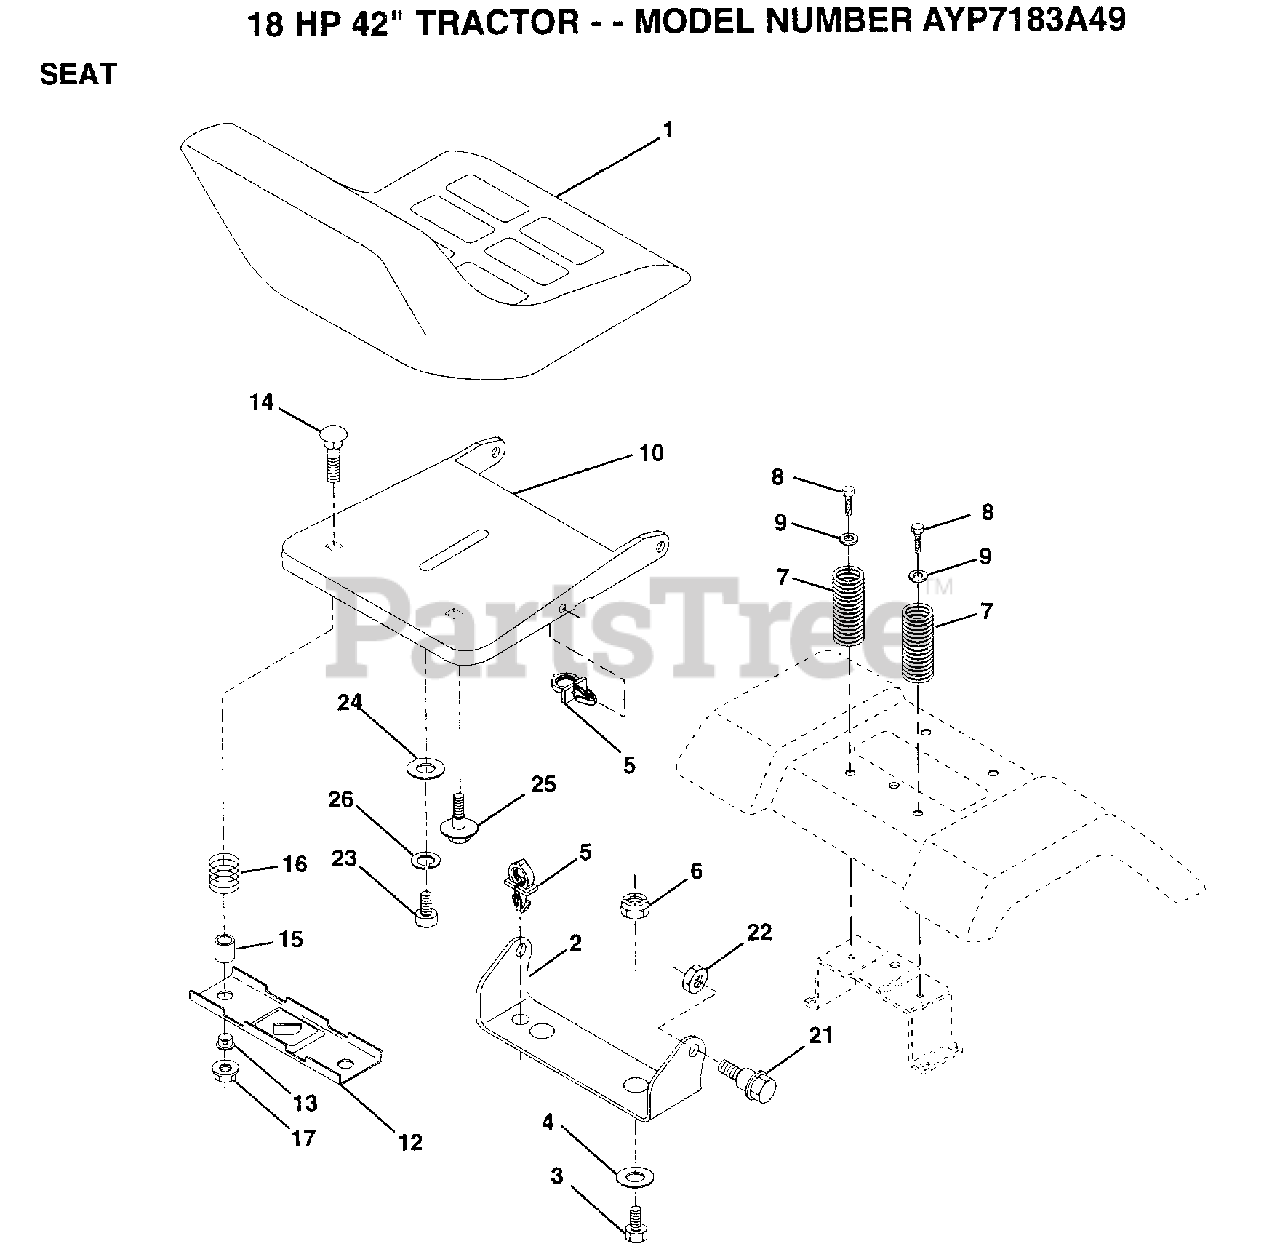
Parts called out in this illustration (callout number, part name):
2	BRACKET PVT SEAT
4	WASHER PM
5	CLIP PUSH - IN
6	NUT
7	SPRING COMPRESSIO
8	SCREW GTV
9	WASHER
11	STRIP FORM
12	BRKT SWITCH
13	BUSHING
15	SPLIT SPACER
16	SPRING
21	BOLT.SHLD.5/16-18
23	BOLT
24	WASHER
25	"BOLT,SHOULDER"
26	LOCKWASHER
